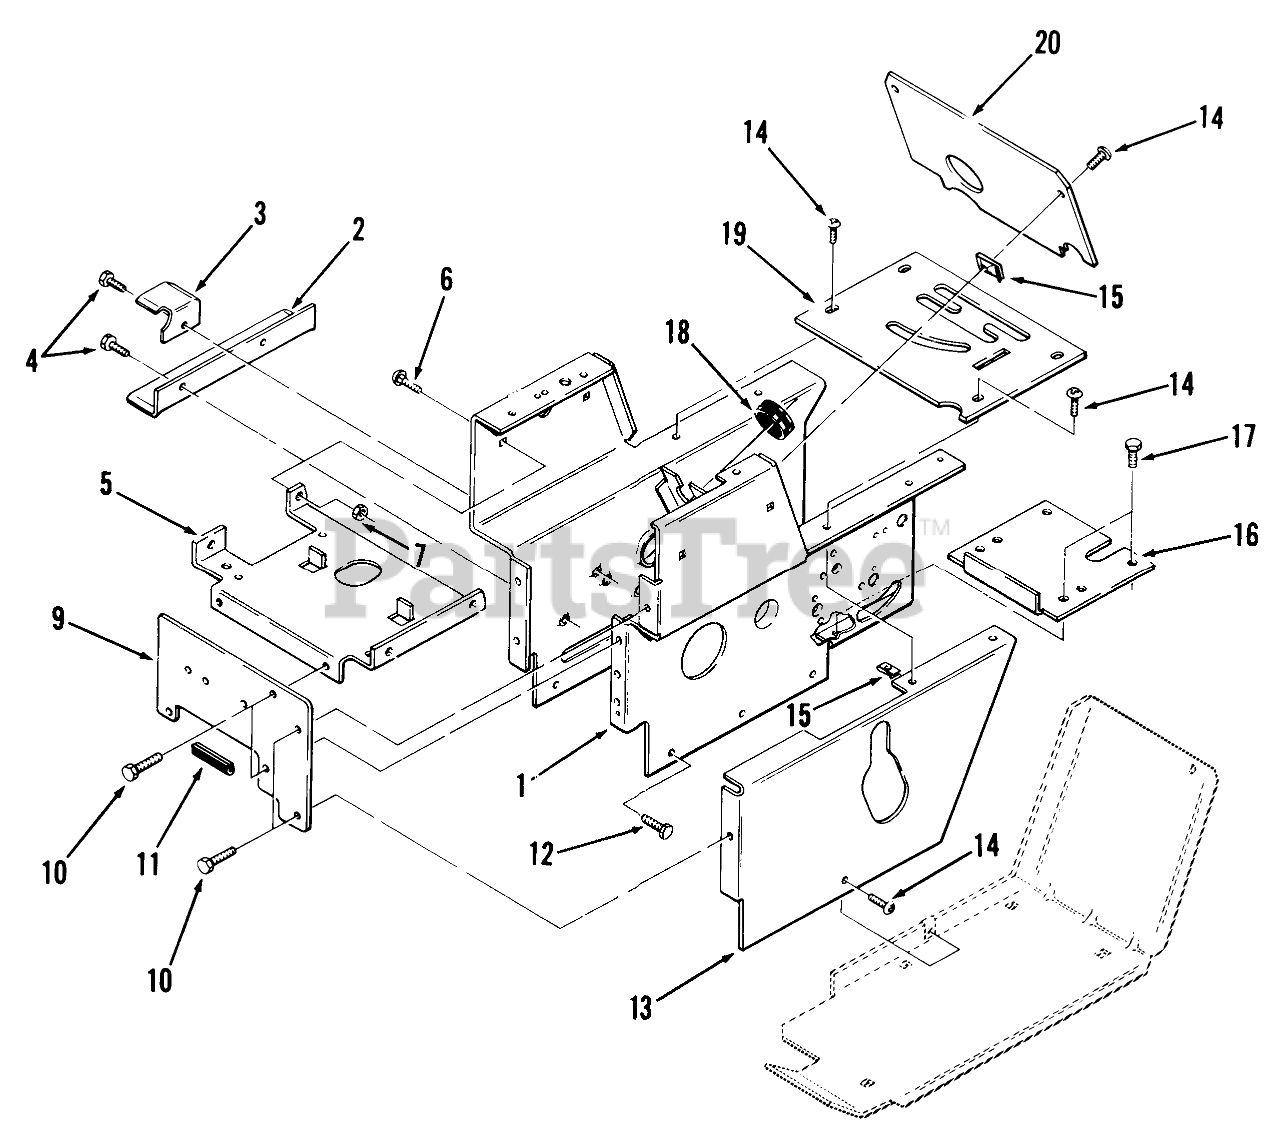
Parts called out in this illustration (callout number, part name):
1	Hoodstand
2	ANGL-BLT GURDB
3	Belt Bracket
4	SCREW
5	Battery Support Bracket
6	CARRIAGE BOLT -4
7	Nut
9	Front Plate
9	Front Plate C-161 Twin Only
10	SCREW
11	EDGE TRIM 2" 102896
12	Bolt
13	Side Cover LH
14	Screw
16	Cover-Dust
17	SCREW
18	GROMMET
19	Shift Cover Plate C-121 Only
19	Shift Cover Plate C-141, C-161 Only
19	Shift Cover Plate
19	SHIFT PLATE
19	PLATE-SHIFT PATTE B
20	Ammeter Plate
20	PLATE-HOODSTAND REAR
